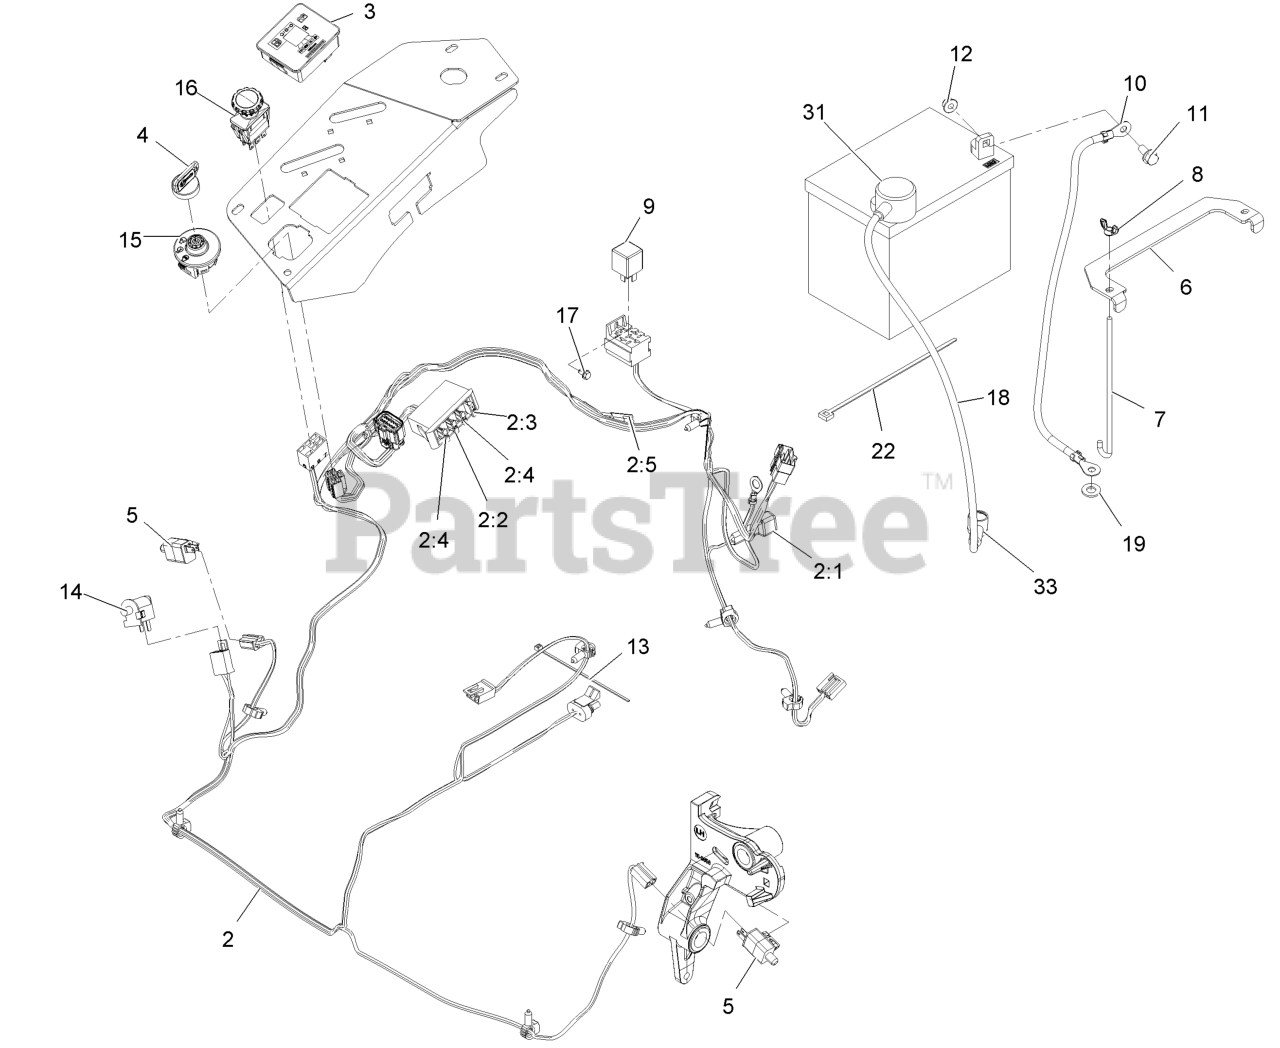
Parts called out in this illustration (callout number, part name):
2:2	FUSE-BLADE, 10 AMP
2:3	FUSE-BLADE, 15 AMP
2:4	FUSE-BLADE, 25 AMP
2:5	CAP-PLUG
3	FUEL/HOUR METER ASM
4	KEYS-IGNITION (SPARE PAIR
4	KEY-IGNITION
6	STRAP-TIE DOWN, BATTERY
7	BOLT-HOLDDOWN
8	WINGNUT
10	CABLE-BATTERY, NEGATIVE
11	SCREW-HHF
12	NUT-HF, NI
13	TIE-CABLE
14	SWITCH-BAIL
16	SWITCH-PTO, 10 AMP
17	SCREW-HWH
18	CABLE-BATTERY, POSITIVE
19	WASHER-FLAT
22	TIE-PLASTIC
31	INSULATOR-BATTERY
33	INSULATOR-SOLENOID
